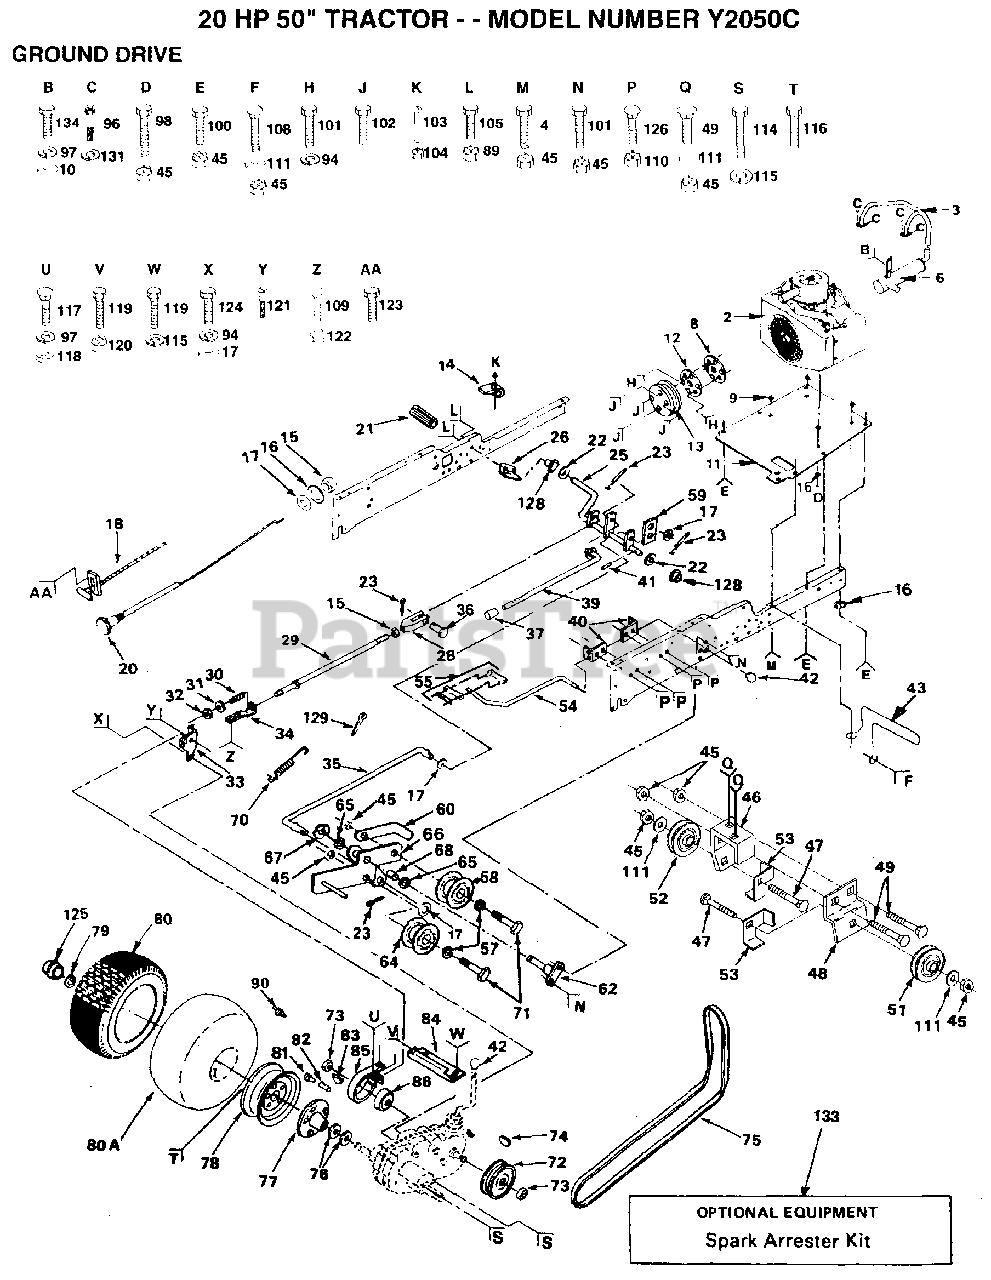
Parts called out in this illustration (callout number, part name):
2	ENGINE, MODEL KOHLER
3	EXHAUST TUBE T
4	"BOLT,HEX"
6	MUFFLER EXHAUST
8	CHAFF GUARD T
9	SPACER.ENGINE KOH
11	"ENG. T, BASE"
12	ADAPTER T
14	ACT-SWITCH T
16	LOCKWASHER
17	WASHER
21	PEDAL COVER T
22	WASHER
25	SHAFT ASSY GT
26	BRKT SWITCH GT
28	YOKE GTV
29	BRAKE ROD T
30	SPRING T
31	WASHER
33	BRAKE BRKT ASSY T
34	GUIDE ROD T
35	ROD CLUTCH GTV
36	CLEVIS PIN T
37	PLUNGER CAP T
39	BRAKE ROD
40	ROD BRACKET GT
41	ROLL PIN STD
42	KNOB
43	GUARD MUFFLER HYT
47	BOLT
48	BRKT IDLER FLAT
49	BOLT
51	IDLER-FLAT T
52	PULLEY V IDLR GTV
53	GUARD BELT
54	ROD SHIFT HI LO
55	CONNECTING LINK
57	WASHER
59	RETAINER SPRING
60	RETAINER BELT
62	BRACKET ASSY GTV
65	WASHER T
66	BRACKET CLUTCH
67	KLIP RING
68	"LY, BEARING"
70	SPRING EXT CLUTCH
73	NUT STD
75	BELT-V.98.5.GD.DV
76	WASHER T
79	KLIP RING
80A	TUBE.23X8/10-12
81	VALVE CAP
82	VALVE STEM LT
85	BRAKE BAND ASM
86	BRAKE DRUM T
89	NUT
90	ZERK FITTING M
94	LOCKWASHER
96	SCREW
97	LOCKWASHER
101	BOLT
102	SCREW
103	SCREW
105	BOLT LT
108	BOLT.3/8-14X1.25
111	WASHER GT
114	BOLT
115	LOCKWASHER
116	BOLT.HUB.WHL.REAR
117	BOLT T
119	BOLT
120	NUT GTV
121	SCREW
123	SCREW LT
125	"COVER, HUB"
126	BOLT
128	NYLINER T
129	COTTER PIN
133	SPARK ARREST KIT
